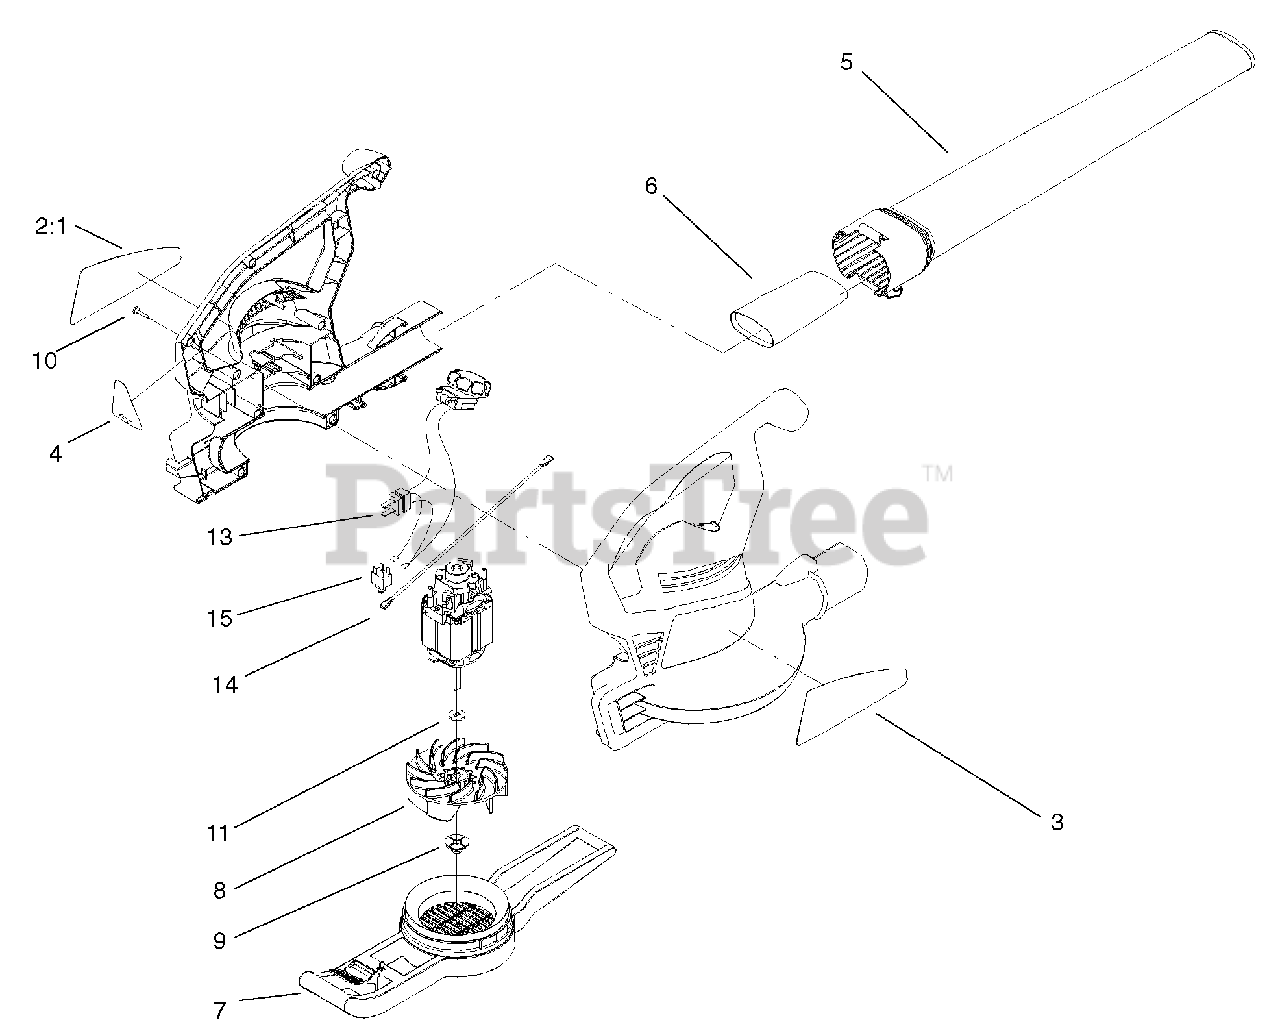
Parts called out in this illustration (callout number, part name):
2	Decal-Serial, Ultrablower
2:1	Label Stock-Serial
3	DECAL-ULTRABLOWER
4	DECAL-LOCK, CORD
5	TUBE-BLOWER
6	TUBE-INSERT
7	COVER-INLET
8	Impeller-Magnesium
9	NUT-HEX
10	SCREW-PPH
13	WIRE HARNESS ASM
15	SWITCH-INTERLOCK
